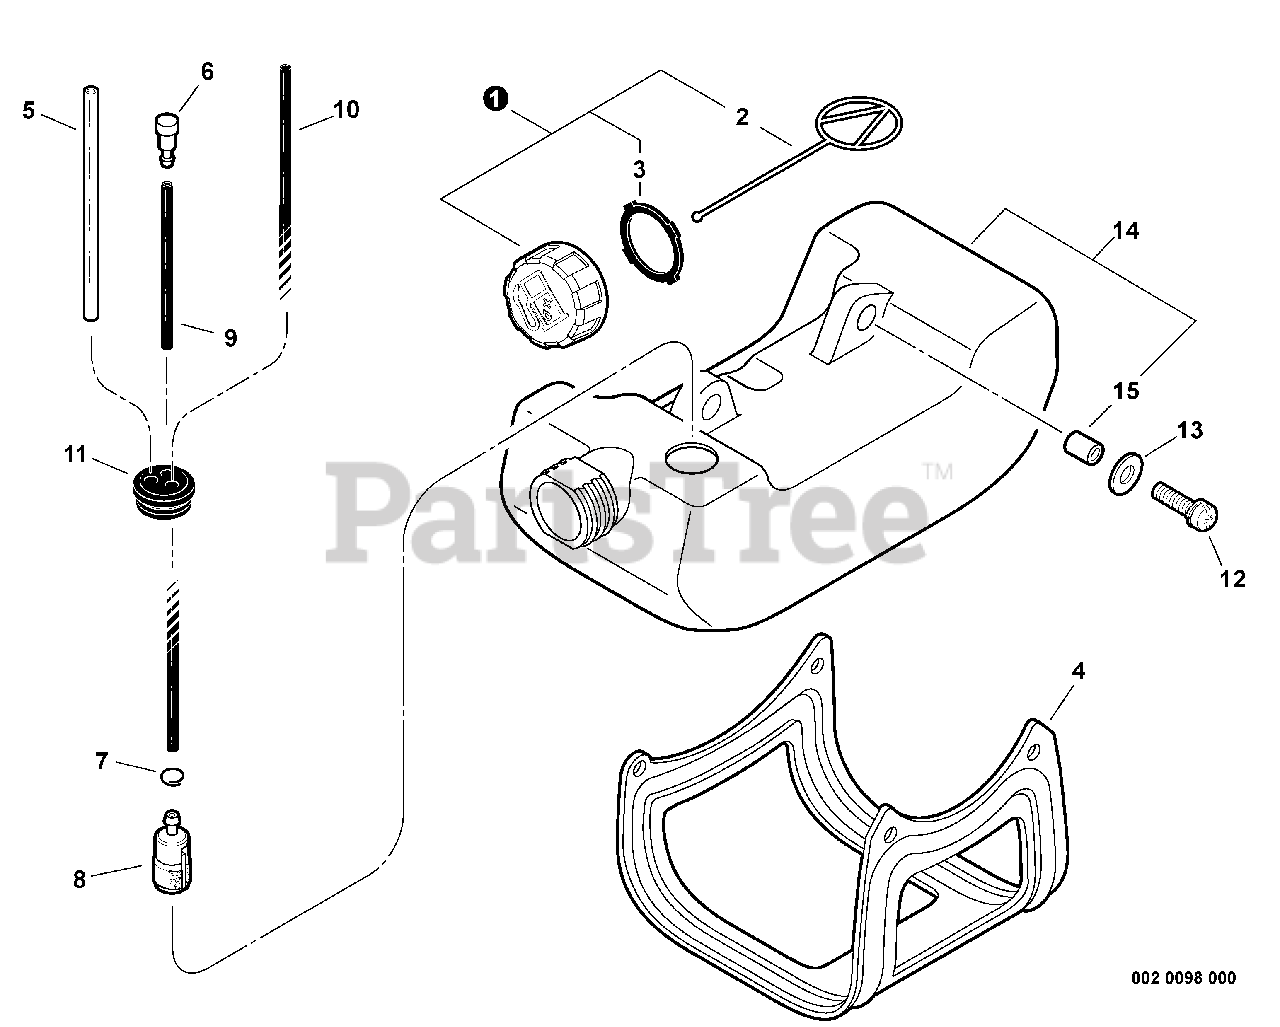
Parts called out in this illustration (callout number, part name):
1	CAP ASSY
2	CONNECTOR, CAP
3	GASKET, CAP
4	GUARD, FUEL TANK
5	PIPE - 3X6X90 -- CLEAR
6	VENT, FUEL TANK
7	CLIP - 6
8	FILTER, FUEL
9	PIPE - 3X5X70 -- BLACK
10	PIPE - 3X5X180 -- BLACK
12	SCREW - 5X16
13	WASHER - 5
14	FUEL TANK ASSY
